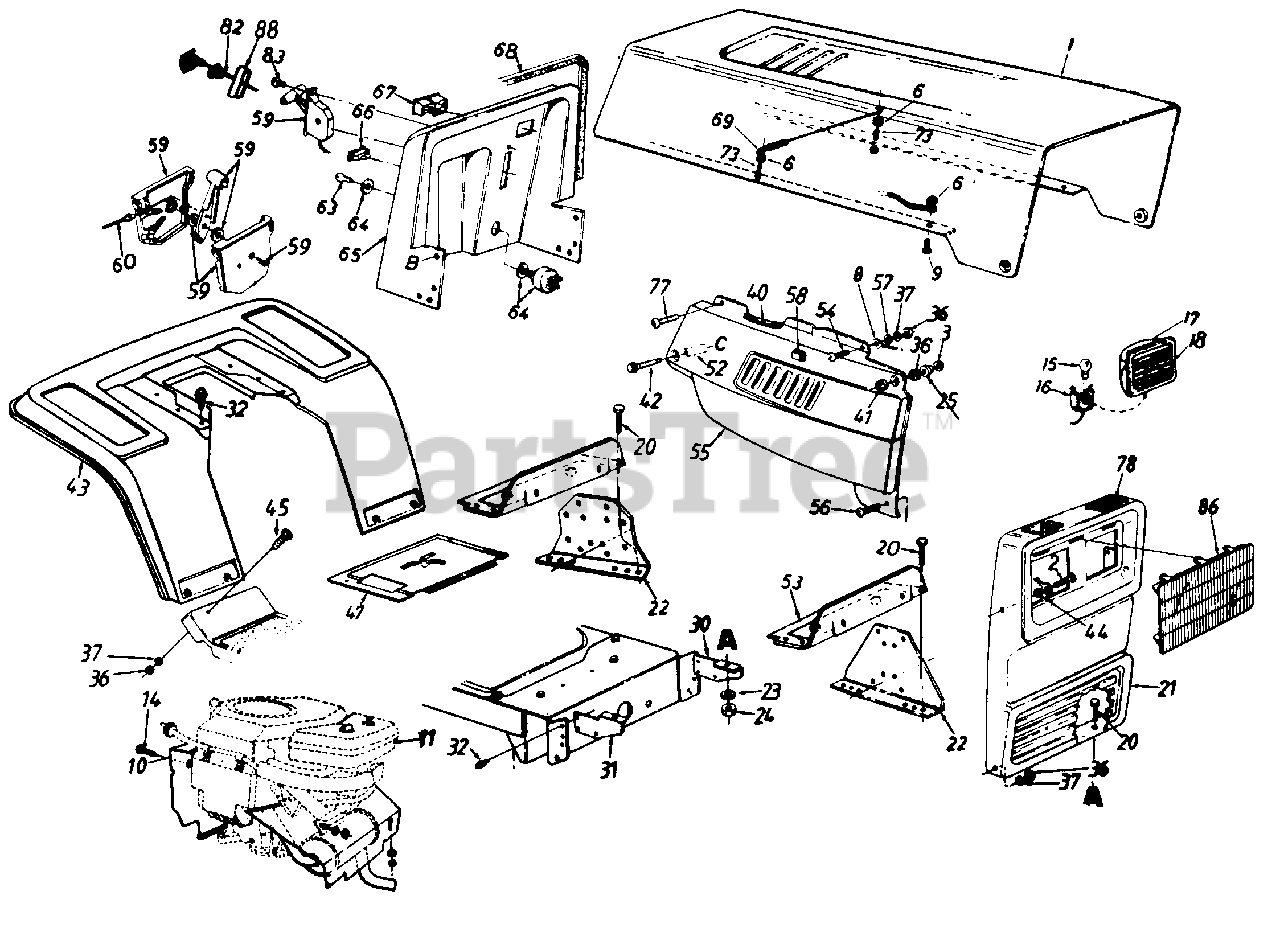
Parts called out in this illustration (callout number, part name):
1	Hood
2	Hex 8elt 1/4-20 x .88" Lg.
3	Washer.39" I.D. x .62"
6	Hex Sems Nut #10-24 Thd.*
8	Hood Stop
9	Truss Hd. Scr. #10-24 x 1/2"*
10	Baffle w/Trim Strip
11	Engine
14	Hex Tap Scr. 1/4-20 x .5" Lg.
15	Bulb
16	Twist Lock-Bulb Socket
17	Headlight Housing
18	Lens
20	Hex Bolt 5/16-18 x .75" Lg.*
24	Hex Nut 5/16-18 Thd.*
25	Shld. Spacer
30	Grille Mount Brkt.-L.H.
36	Hex Nut 1/4-20 Thd.*
37	L-Wash. 1/4" I.D.*
40	Trim Strip-12" Lg.
41	Acron Nut 1/4-20 Thd.
42	Hex TT-Tap Scr. 1/4-20 x 1.75" Lg.
45	Truss Mach. Scr. 1/4-20 x .5" Lg.
47	Transmission Panel
52	Spacer 1.30" Lg.
53	Support Brkt.
54	Truss Hd. Scr. 1/4-20 x .75"
57	Fl-Wash. .281" I.D. x .73" O.D.
58	Mounting Clamp
59	Throttle Control Box Ass'y.
60	Throttle Control Wire
63	Ignition Key
64	Ignition Switch
67	Ammeter
68	Trim Strip-31"
69	Hood Spring
73	Hex Scr. #10-24 x 1.0" Lg.
77	Hex Wash. Hd. Tap Scr. 1/4 x .75" Lg.
78	Foam Strip 3/8 x 1-1/8" x 1-1/2 Lg.
82	Choke Control 46" Lg.
83	Truss Mach. AB-Tap Scr. #10 x .5" Lg.
86	Headlight Bezel
88	Retainer Clip
